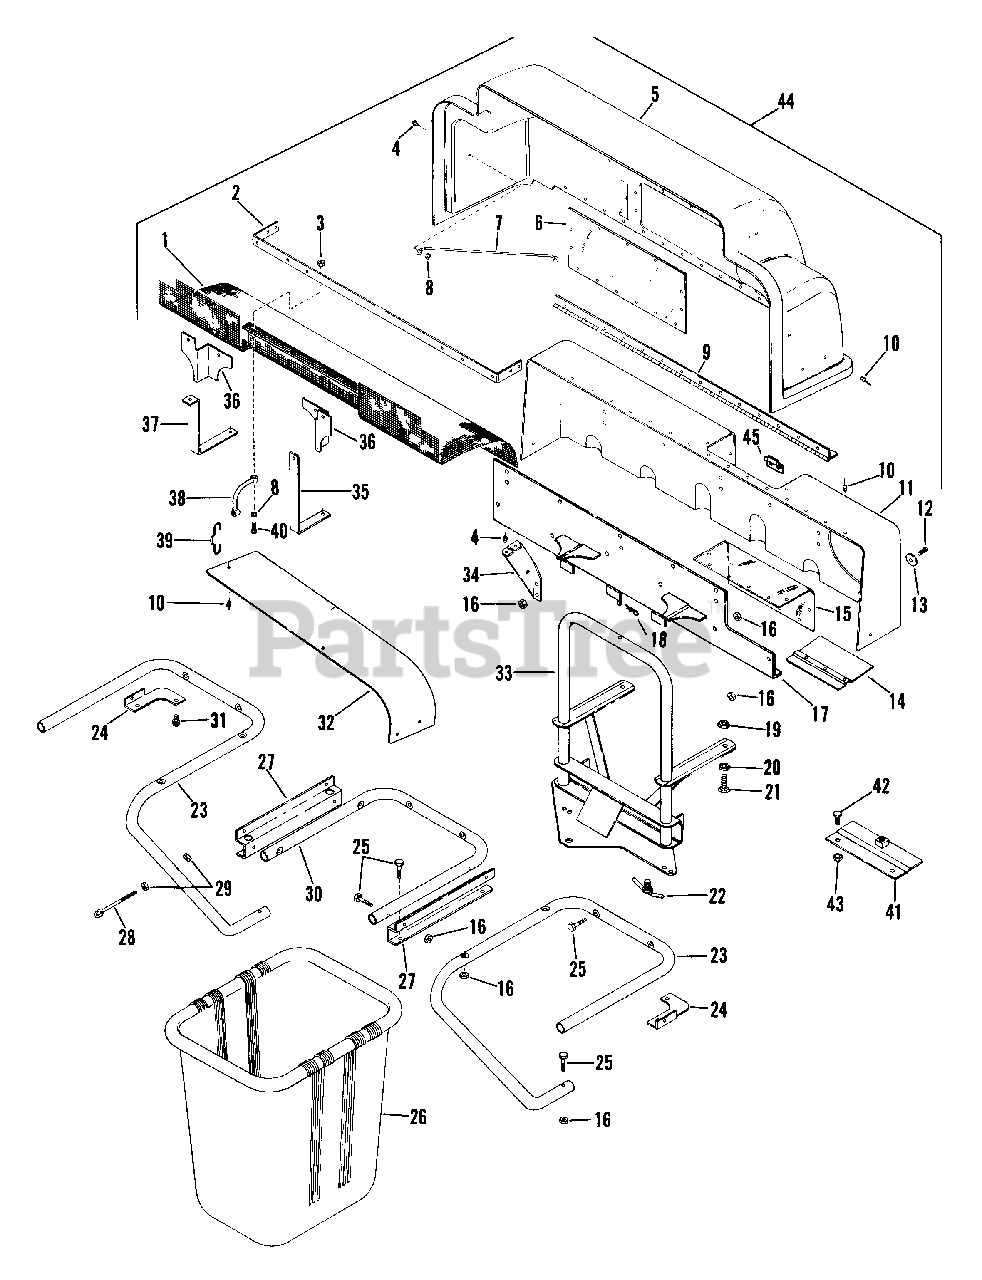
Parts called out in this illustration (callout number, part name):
2	SCREEN MOUNTING BRACKET
3	NUT-LK TOP 10-24 PL
4	RVT-POP.187X.527 DOME ST
5	HINGED COVER W/DECALS
6	HINGED COVER WINDOW
8	WSHR-FL-STL .194X.492X.047 PL
9	HINGE- 2.0"X35.0"
10	RVT-POP .187X.402 DOME ST
11	STATIONARY COVER
12	BLT-HEX .31-18X.88 PL GR2
13	WSHR-FL-STL .344X1.125X.063PL
14	TUBE GUIDE
15	STATIONARY COVER WINDOW
16	NUT-LK-NYL.312-18 PL
17	MOUNTING BRACKET
18	PIN-HAIR INT .08X.38X1.42 YWZC
19	NUT-LK-FLG .375-16 PL
20	NUT-HEX .375-16
21	BLT-HEX .38-16X1.25 PL GR5
22	T-HANDLE BOLT
23	RIGHT TUBE
23	LEFT TUBE
24	RH CORNER BRACKET
24	LH CORNER BRACKET
25	SCR-MCH .31-18X1.50 CROVCNTRS
26	GRASS BAGGER BASKET
27	TUBE BRACKET
28	EYEBOLT
29	NUT-LK-CTR .250-20 PL
30	DASH PANEL W/SILK SCREEN
31	SCR-TAP .312-18X.50 HWH PL TR
33	ATTACHMENT FRAME
36	BAFFLE LH
36	BAFFLE RH
38	BATTERY STRAP
40	SCR-MCH 10-24X.88 SLRH PL
41	ADAPTER WELD'T
42	BLT-HEX .38-16X.75 PL GR5
43	NUT-LK-CTR .375-16 GR A PL
44	STATIONARY COVER
45	BOOT CLIP
